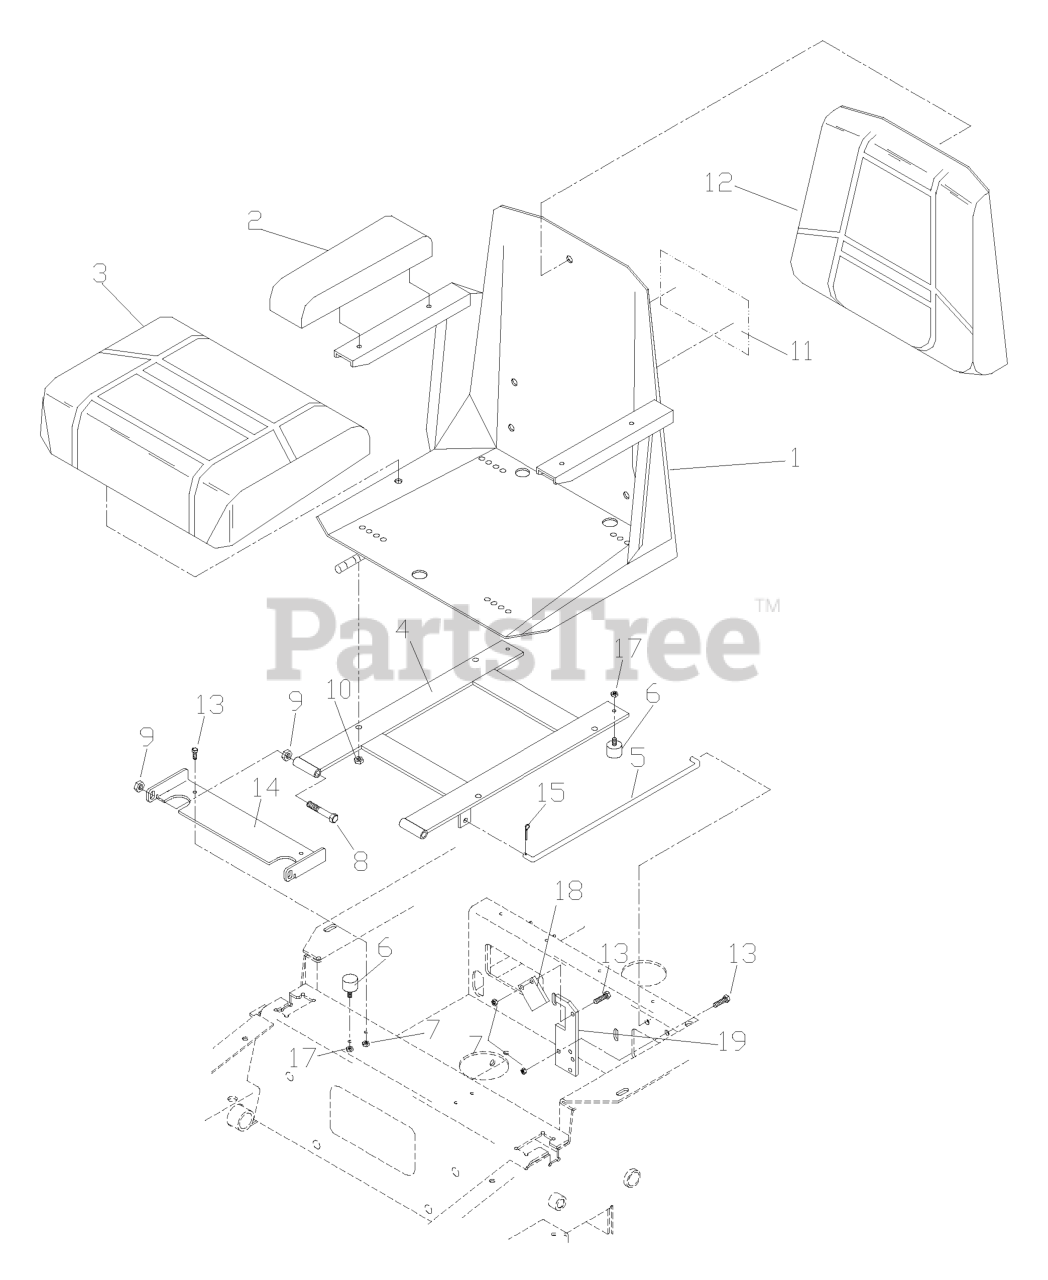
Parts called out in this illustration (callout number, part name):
1	SEAT COMPLETE
2	ARMREST KIT, RH
3	SEAT CUSHION KIT
4	SEAT MOUNT
6	STUD/PLATE MOUNT
7	NUT 1/4C CENTER LOCK
8	HCS 3/8C X 3
9	NUT 3/8C CENTERBLOCK
10	NUT 5/16 NYLOC
11	DECAL, CROWN H
12	BACK CUSHION KIT
13	HCS 1/4C X 3/4 HCS
14	SEAT BRKT W/DECAL
15	RP_COTTER PIN 1/8 X 3/4
17	NUT.1/4-20.HEX.NYLOC.ZD
18	SEAT LATCH
19	SEAT LATCH BASE
